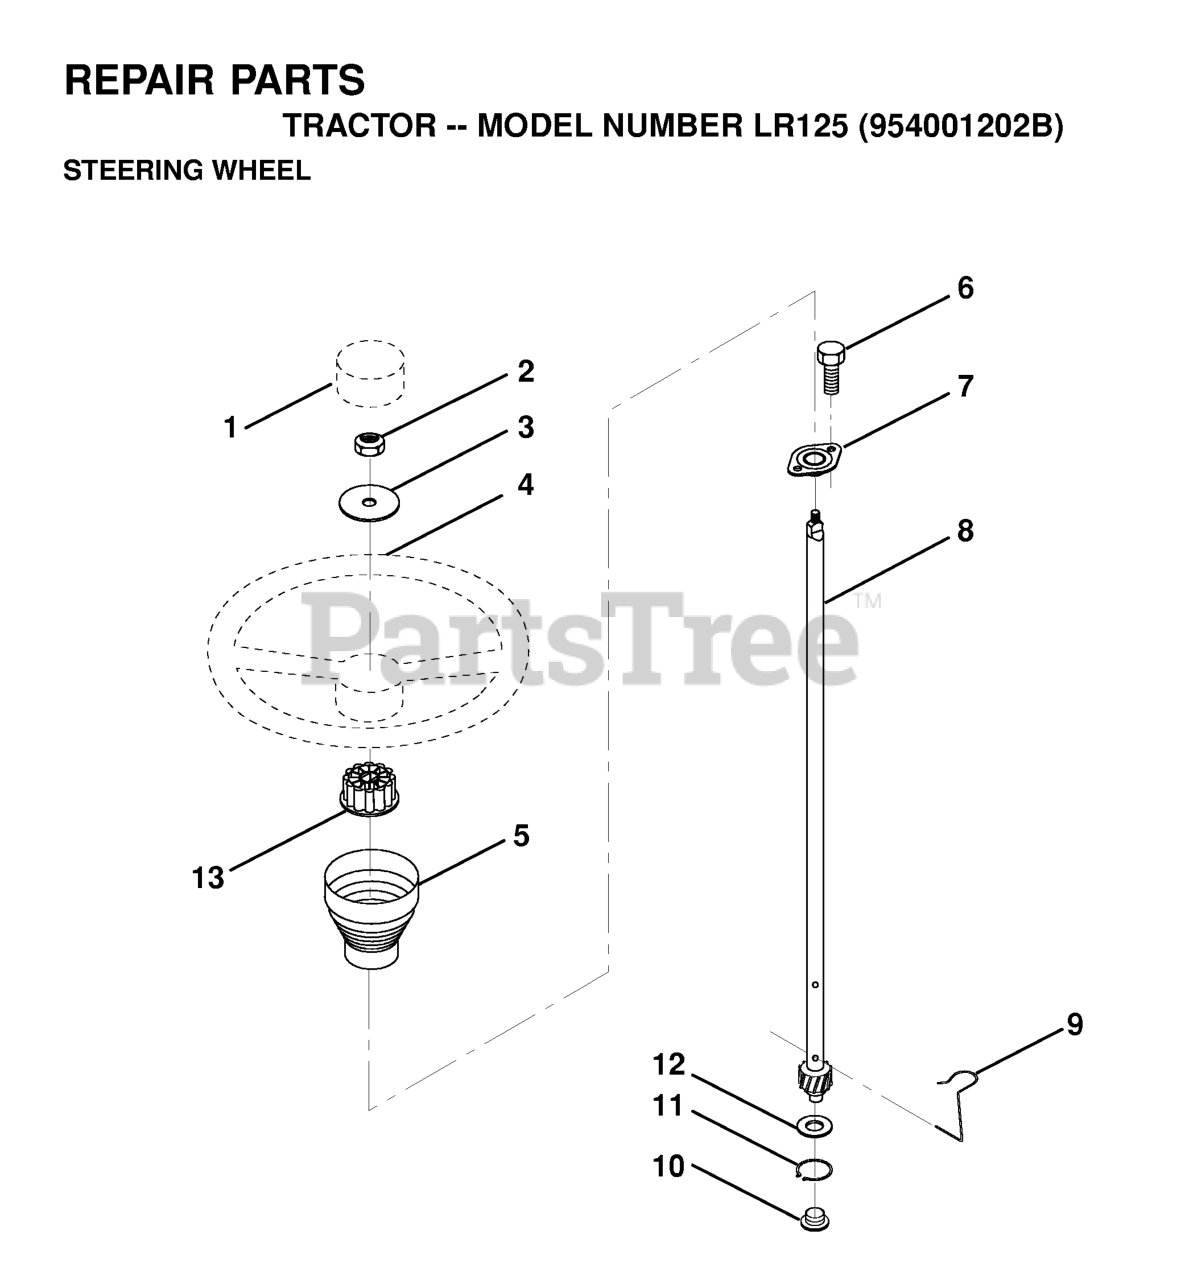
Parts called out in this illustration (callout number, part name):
1	INSERT,STR WHEEL
2	GRIPCO NUT
3	WASHER T
4	STEERING WHEEL
5	STEERING SLEEVE
6	SCREW LT
7	BUSHING-STRG LT
8	SHAFT STEERING
9	STEERING CLIP
10	BUSHING STEER LWR
13	ADAPTER-WHEEL LT
